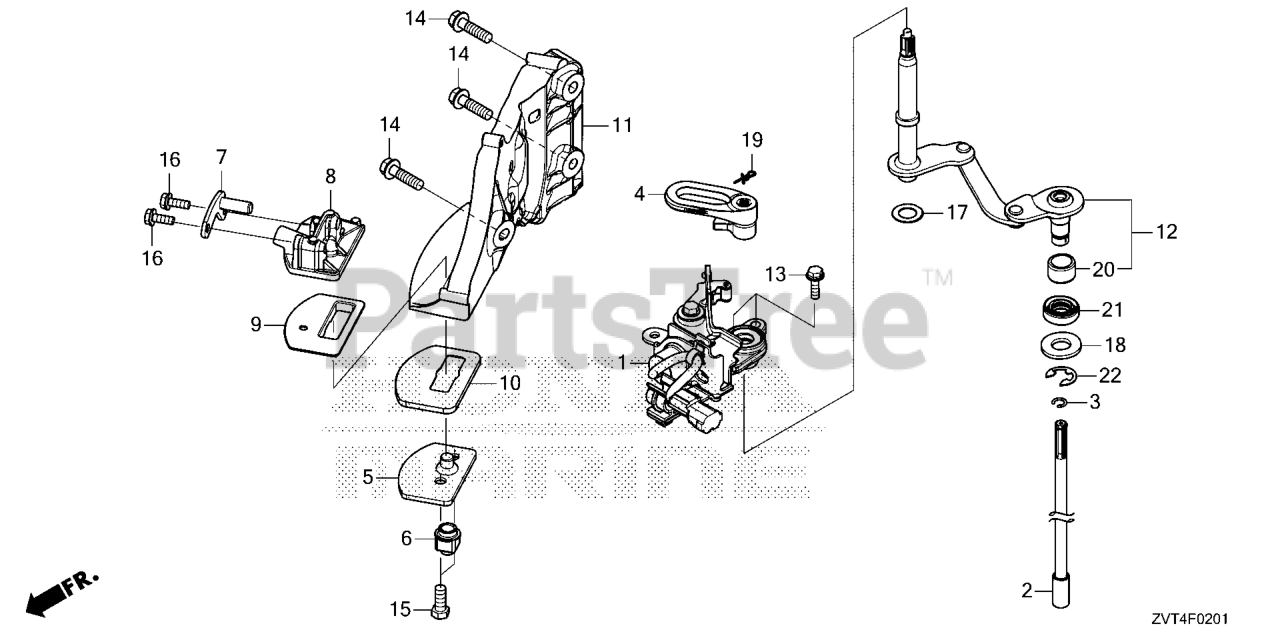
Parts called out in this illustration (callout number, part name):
1	SHIFT-NEUTRAL *NH8*
2	ROD A, SHIFT (L)
3	RING, STOPPER
4	ARM, SHIFT
5	PIN, SHIFT LINK
6	ROLLER, SHIFT
8	PIVOT, SHIFT
9	SLIDER A, SHIFT
10	SLIDER B, SHIFT
11	GUIDE, SHIFT LINK
12	SHAFT COMP, SHIFT
13	BOLT, FLANGE (6X20)
14	BOLT, FLANGE (8X30)
15	BOLT, HEX. (8X20)
16	BOLT, FLANGE (6X16) (SUS)
17	WASHER B, THRUST (14MM)
19	PIN, SNAP (6MM)
20	RING (INNER) (15X20X13)
21	SEAL, WATER (14X26X8)
22	E-RING (12MM)
